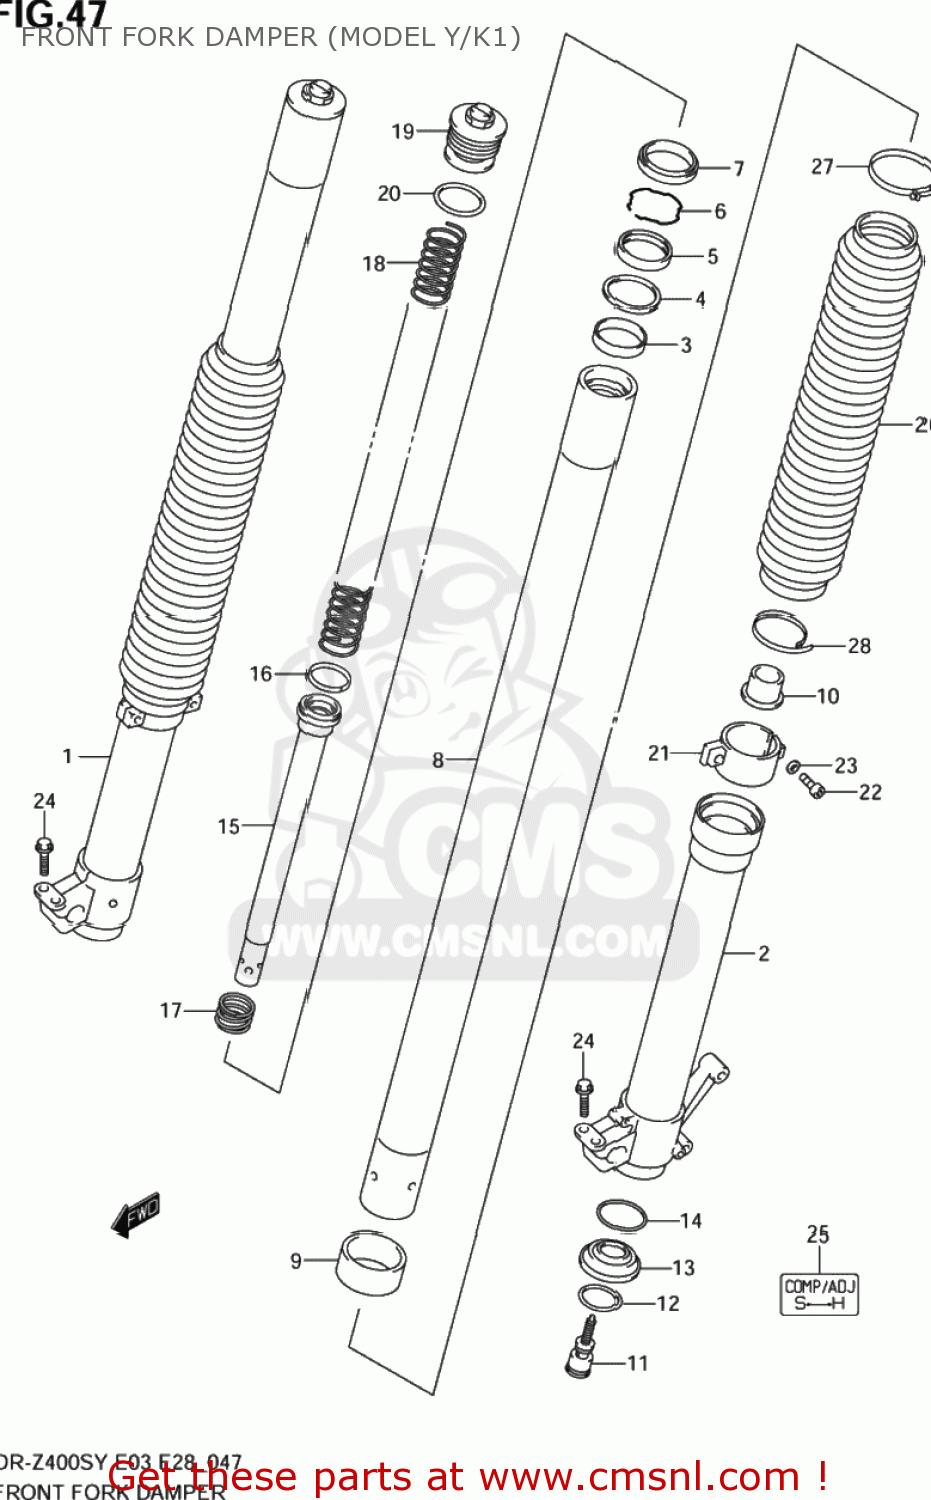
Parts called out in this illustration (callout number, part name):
1	TUBE,OUTER,R
2	TUBE,OUTER,L
3	BUSH,GUIDE
4	SPACER,SEAL
5	SEAL,OIL
6	RING,STOPPER
7	SEAL,DUST
8	TUBE,INNER
9	BUSH,SLIDE
10	PIECE,OIL LOCK
11	BOLT,CTR
12	PACKING (NAS)
13	PLATE,END
14	O RING
15	CYLINDER
16	RING,PISTON
17	SPRING,REBOUND
18	SPRING,FR
19	BOLT
20	O RING
21	HOLDER,BOOT
22	BOLT
23	WASHER(5.5X10X1)
24	BOLT,HANDLE HOLDER(8X35)
25	LABEL
26	BOOT
27	BAND,BOOT UPR
28	BAND,BOOT LWR
